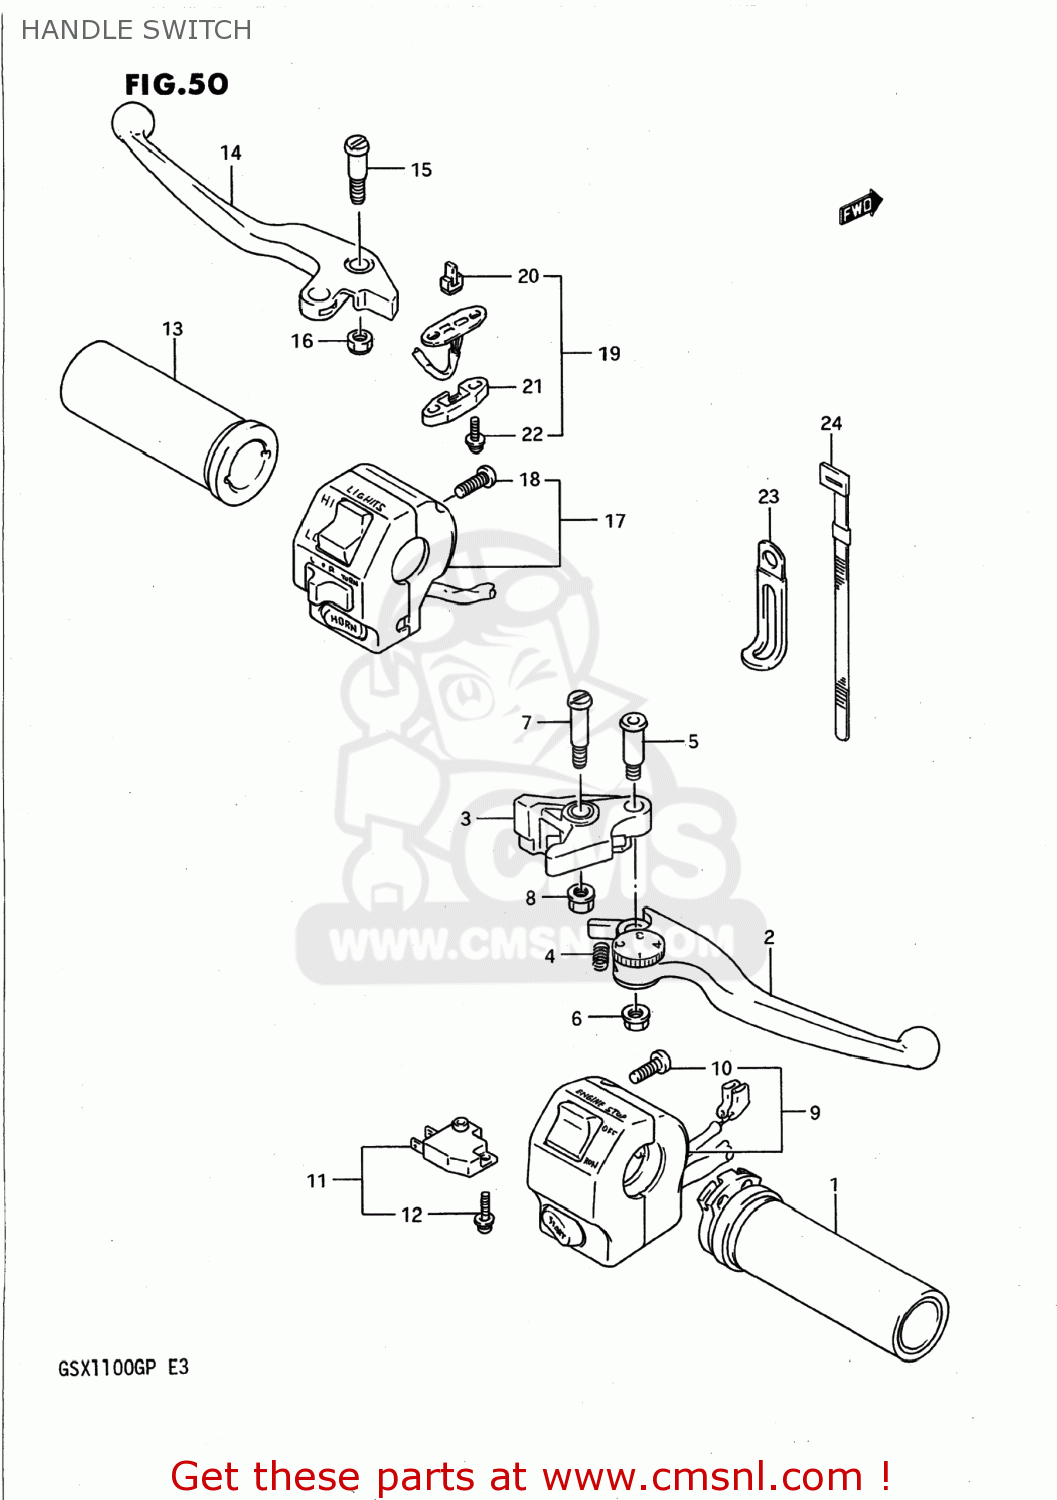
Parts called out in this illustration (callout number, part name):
1	GRIP,THROTTLE
2	LEVER,ADJUST
3	KNOCKER
4	SPRING
5	BOLT,LEVER
6	NUT
7	BOLT,LEVER PIVOT
8	NUT 6MM
9	SWITCH ASSEMBLY,HANDLE,RIGHT
10	SCREW, 5X45
11	SWITCH ASSEMBLY,STOP
12	SCREW
13	GRIP,L
14	LEVER,CLUTCH (SILVER)
15	BOLT,LEVER SET
16	NUT
17	SWITCH ASSEMBLY,HANDLE,LEFT
18	SCREW, 5X45
19	SWITCH ASSEMBLY,CLUTCH
20	CONTACT,SWITCH
21	COVER,FR BK TERMINAL BASE
22	SCREW
23	CLAMP
24	CLAMP(L:120)
